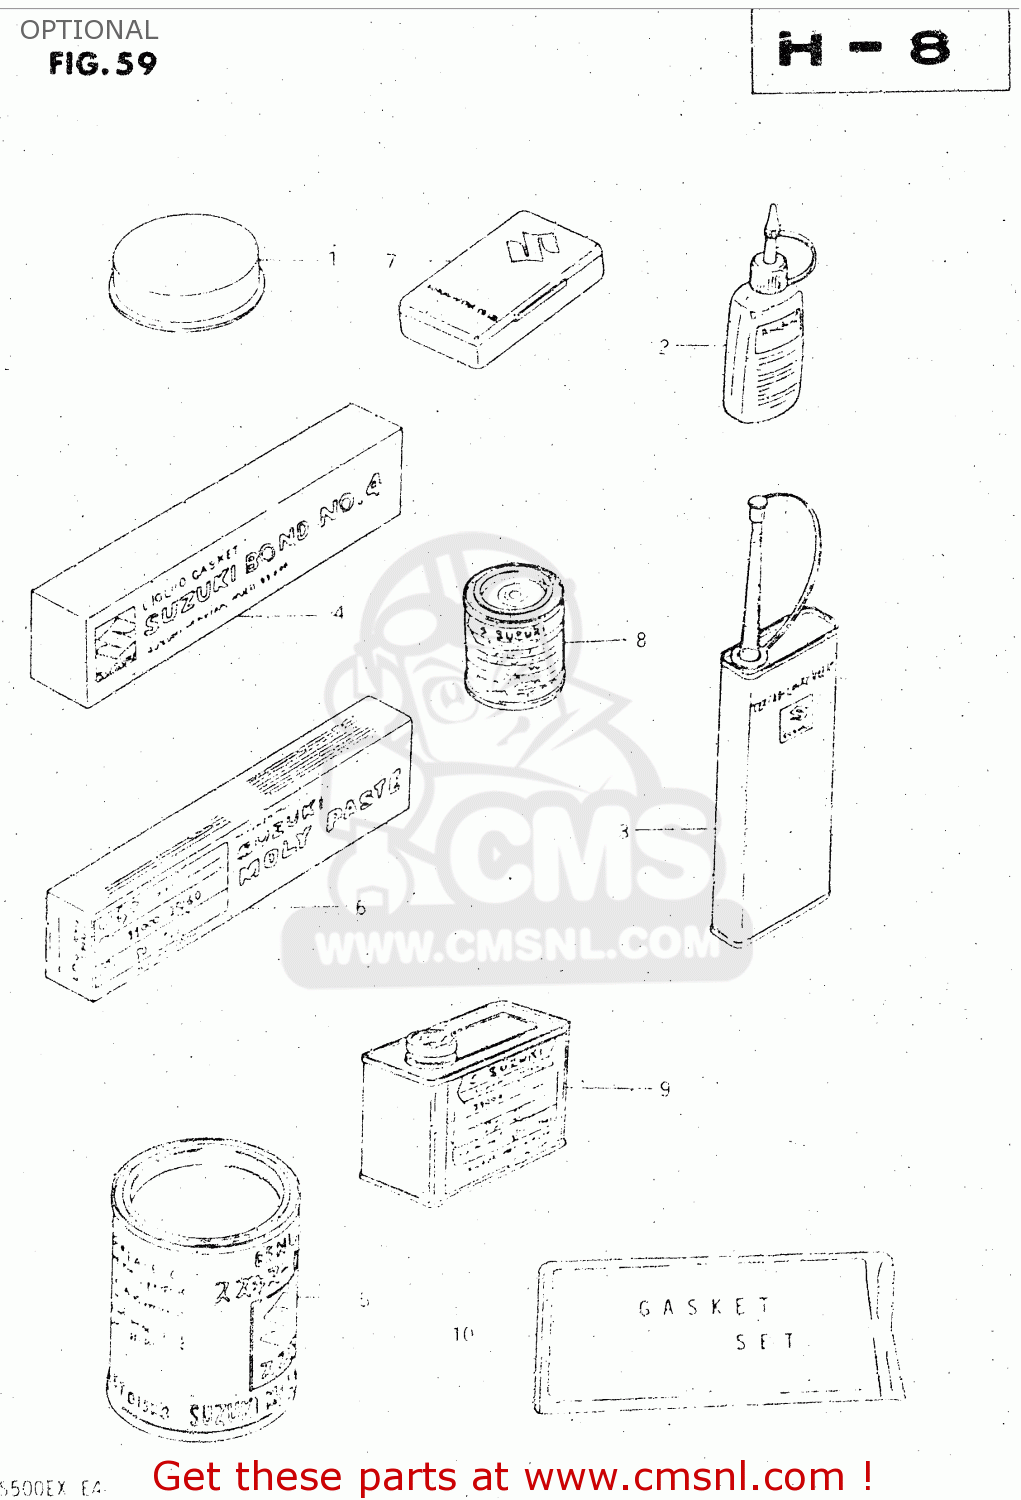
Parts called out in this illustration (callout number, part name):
1	GREASE,PBC FOR BRK PAD 20G
2	THREAD LOCK SUPER (1332B)
3	THREAD LOCK NO.1401 CLEAR 200G
4	BOND 1104
5	GREASE(C)EP2 LITHIUM 150G
6	SUZUKI MOLY PASTE
7	TUBE REPARING TOOL
8	PAINT,BLACK
9	PAINT (BLACK)
10	GASKET SET
